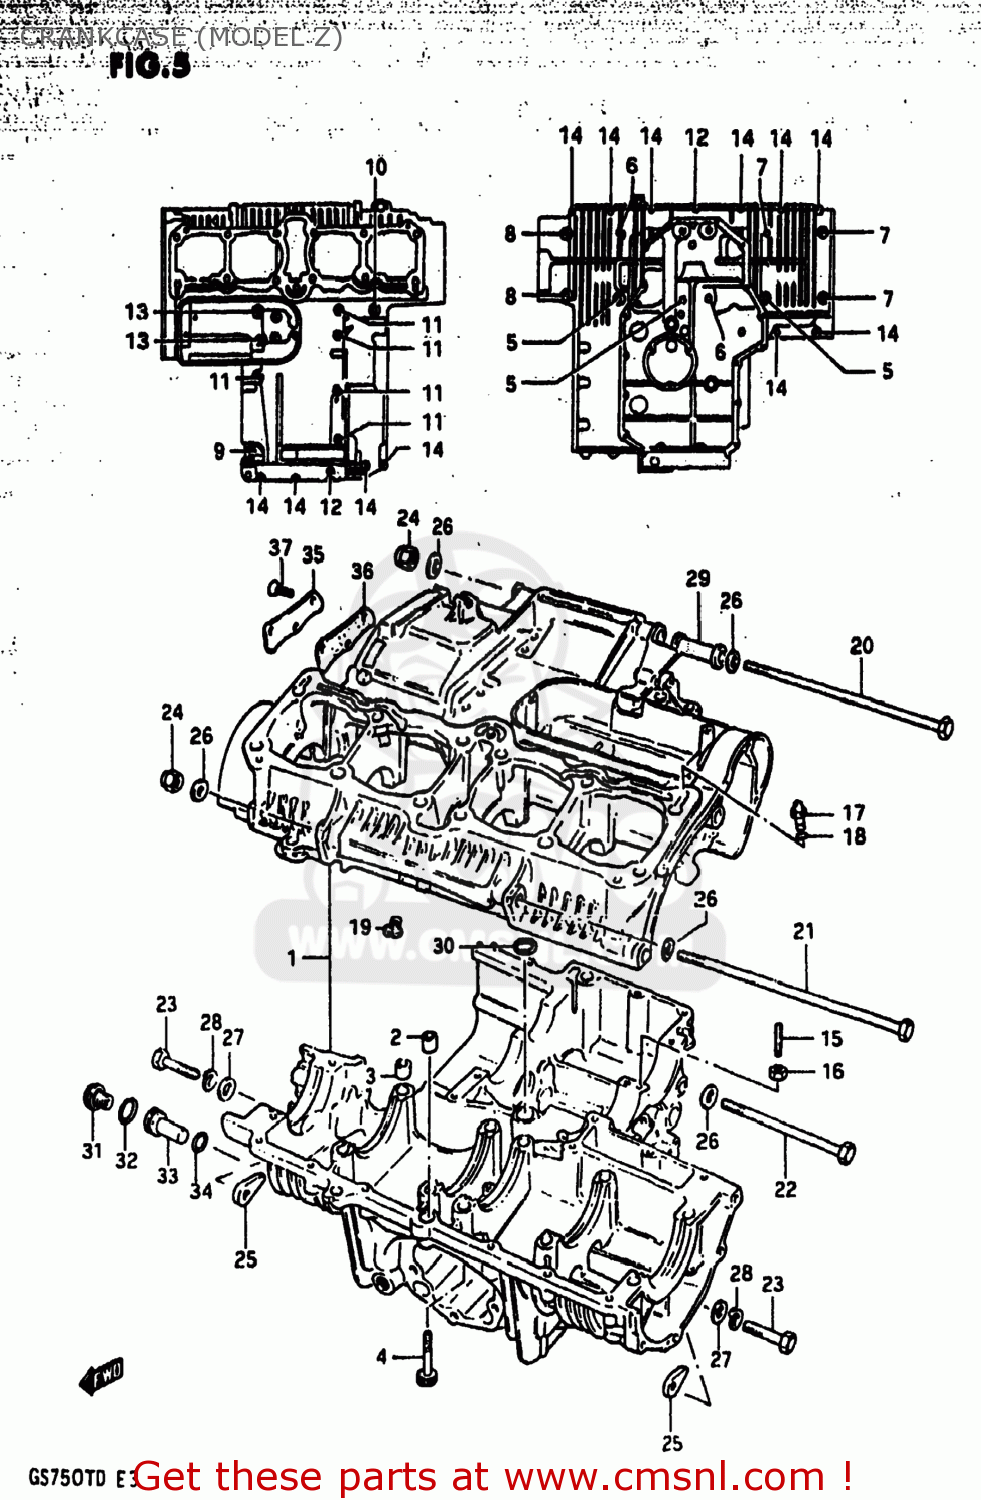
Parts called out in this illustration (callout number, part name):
1	CRANKCASE ASSEMBLY
2	PIN(10.4X13X22)
3	PIN (11X20)(SUS)
4	BOLT
5	BOLT(8X140)
6	BOLT
7	BOLT (8X95)
8	BOLT (8X70)
9	BOLT 8X65
10	BOLT 6X95
11	BOLT (6X80)
12	BOLT (6X60)
13	BOLT,UNDER
14	BOLT
15	STUD BOLT
16	NUT
17	JET
18	O RING(D:1.05,ID:3.1)
19	JET,AIR
20	BOLT 10X230
21	BOLT 10X250
22	BOLT(10X165)
23	BOLT 10X60
24	NUT
25	NUT
26	WASHER
27	WASHER(10.5X20X3.2)
28	LOCK WASHER
29	SPACER,ENGINE MOUNT
30	O RING(D:3.2,ID:12.9)
31	PLUG
32	O RING(D:2.4,ID:17.8)
33	PIN,OIL GALLERY
34	SEAL (D:1.9 ID:9.8)
35	CAP,OIL GALLERY
36	GASKET,OIL GALLERY (MCA)
37	SCREW
